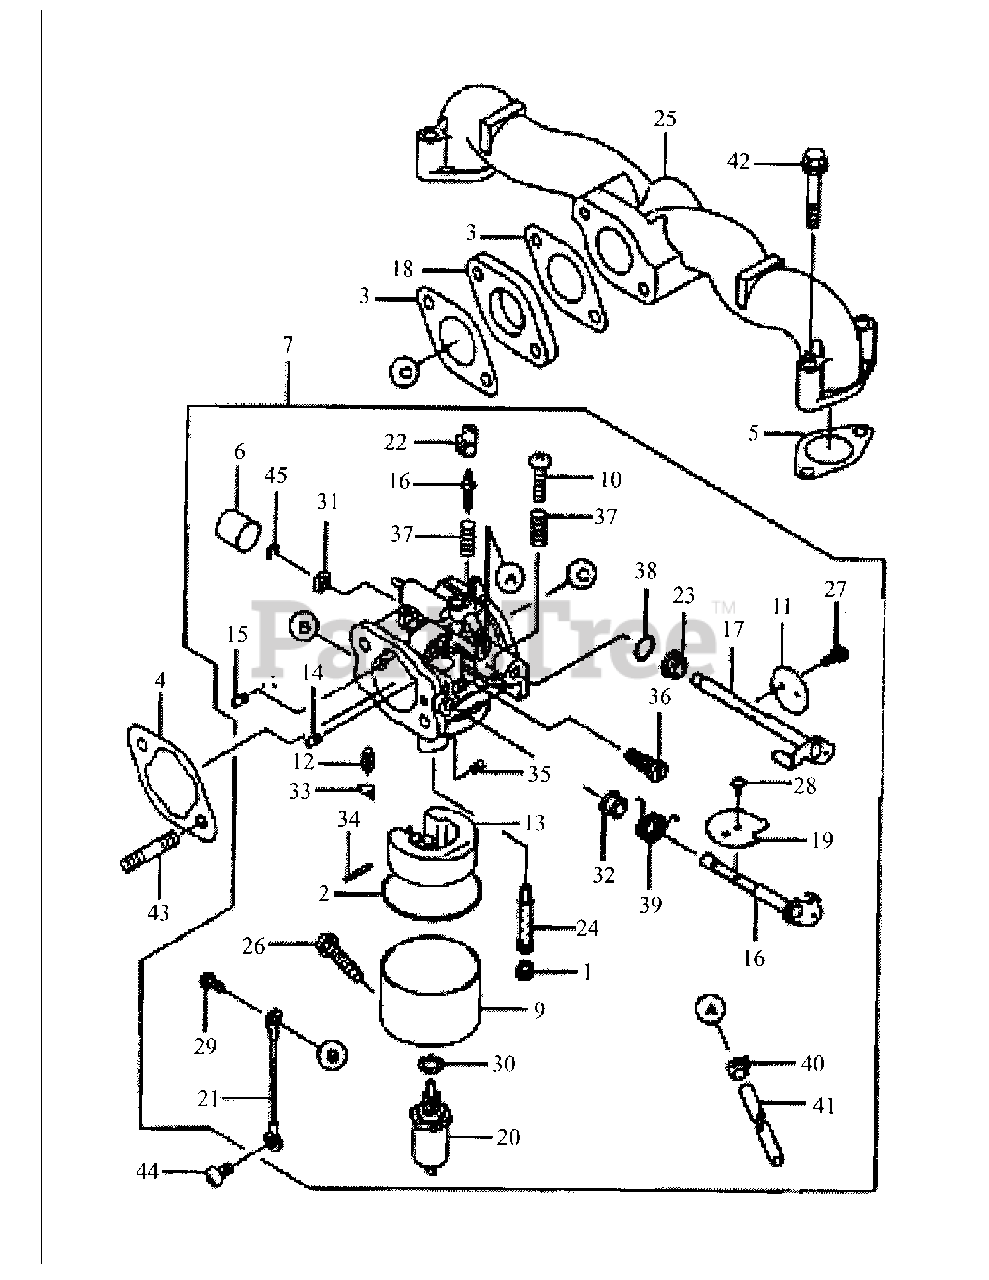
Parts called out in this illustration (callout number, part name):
1	Seat, Valve
3	Gasket, Insulator
4	Gasket, Air Filter
7	Carburetor Assembly
8	Screw, Pilot-Air
9	Chamber, Float
10	Screw Throttle Stop
11	Valve, Throttle
12	Valve, Float
14	Jet, Air #1.7
15	Jet, Air #1.2
16	Shaft, Choke
17	Shart, Throttle
18	Insulator
21	Wire, Lead
24	Nozzle, Main
25	Manifold, Intake
33	Ring, Snap
35	Jet, Main
36	Jet, Pilot
42	Bolt, Flange
43	Bolt, Stud
44	Screw, Pan
45	I Circlip, Type E
